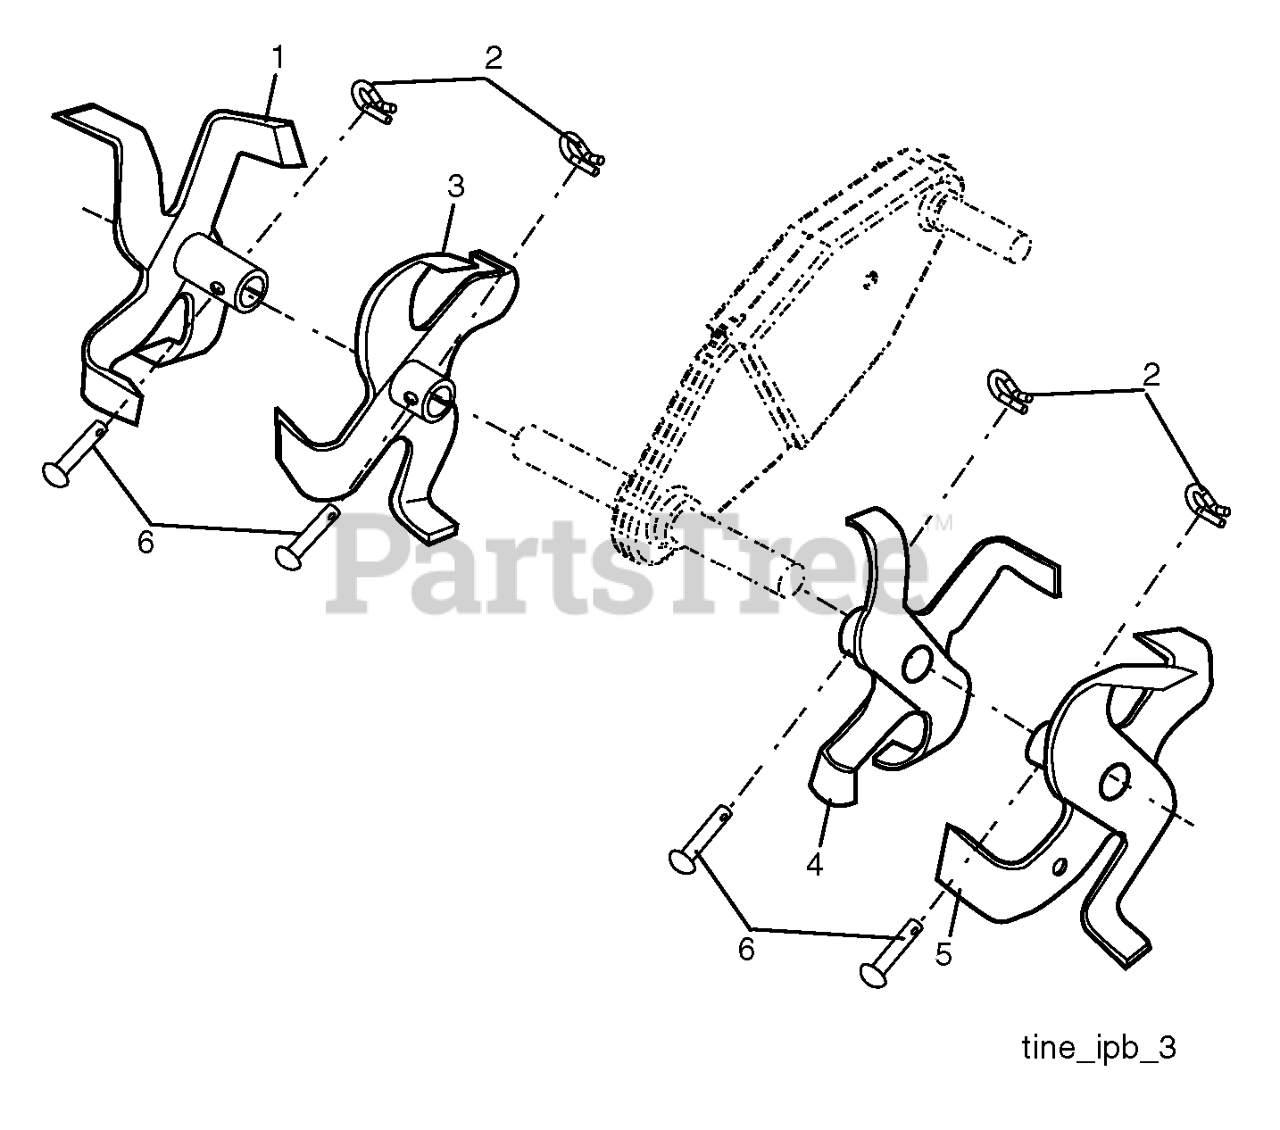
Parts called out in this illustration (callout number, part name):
1	TINE.ASM.OUTER.RH.13.BLACK
2	SPRING RETAINER
3	TINE.ASM.INNER.LH.13.BLACK
4	TINE.ASM.INNER.RH.13.BLACK
5	TINE.ASM.OUTER.LH.13.BLACK
6	RIVET.PAN.HD.DRILLED
